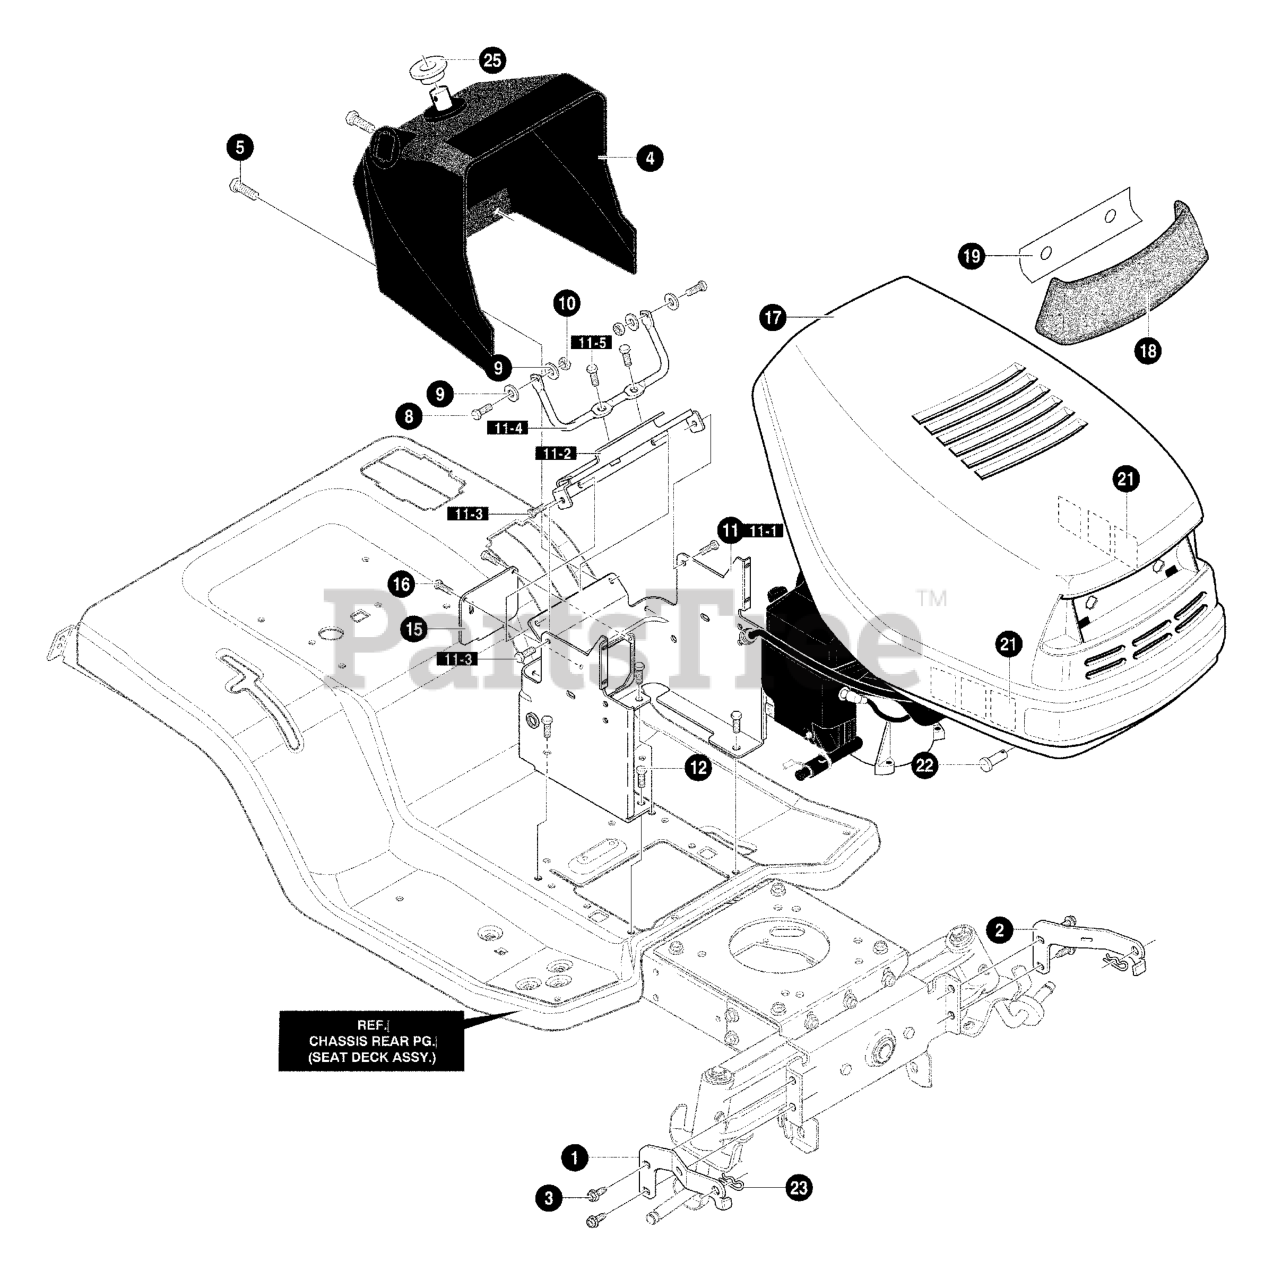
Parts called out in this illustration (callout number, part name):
1	BRACKET, HOOD RH-H15
2	BRACKET, HOOD LH-H15
3	SCREW, 5/16-18 x 0.75
4	DASH, H14/H15
5	SCREW, 1/4-14X .75PHPANTAPABBL
8	SCREW, 1/4-20X .75 HHC
9	WASHER, FLAT .281X .63X.065
10	NUT, 1/4-20 REGHEXCTRLK
11	ASM. LOWER CONSOLE H14/H15
11-1	TOWER, LOWER DASH
11-2	SUPPORT, STEERING/PTO
11-3	SCREW, 1/4-20X .50 WAHHTAP
11-4	ROD, DASH BRACE
11-5	SCREW, 1/4-20X .50 WAHHTAP
12	SCREW, 5/16-18 x 0.75 HHWATAPSGIBP
15	PANEL, ACCESS NLT
16	SCREW, 10-24X.500 TRSEGI ZNBKCR
17	HOOD, NOMA LARGE H-15
18	LENS, HEADLAMP DYNA HOODS
19	FOIL, LENS DYNA HOOD REFLECTOR
21	FOIL, HEAT REFLECTOR
22	PIN, CLEVIS .375DIA.X .81 LG
23	PIN, HAIR.38 DIAX1.64LGPH&OI/Z
25	BUSHING, STEERING SHAFT
